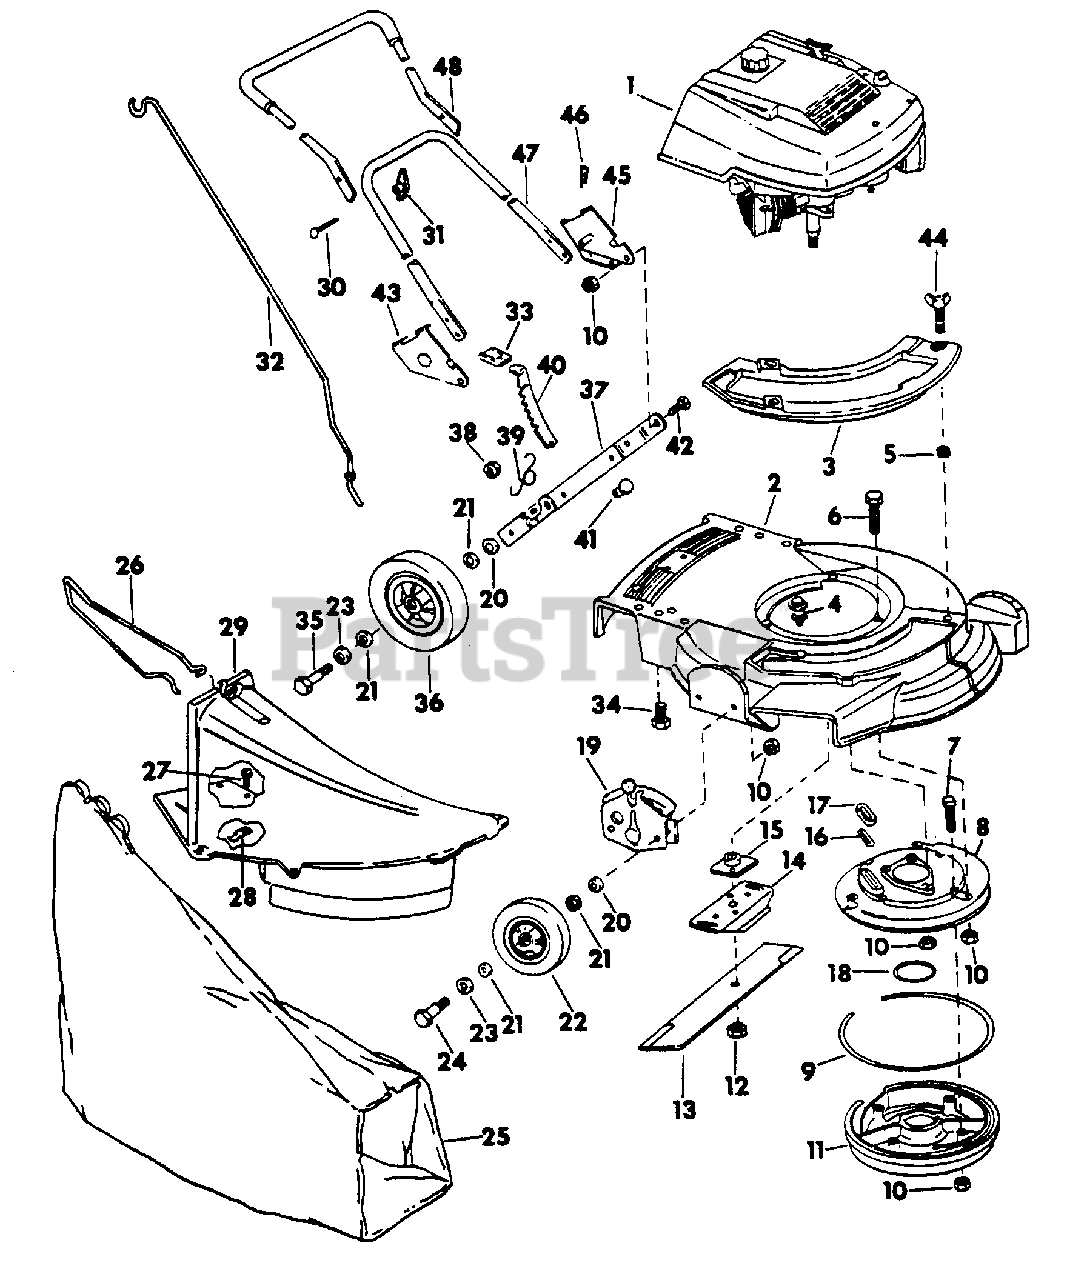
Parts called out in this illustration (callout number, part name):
1	ENGINE, IH
2	HOUSING & GROMMET ASSY. 19 IN.
3	COVER, CHUTE OPENING
4	SCREW, SHOULDER
5	NUT, GROMMET
6	SCREW, MUFFLER PLT TO HSG
7	SCREW, MUFFLER TO PLATE
8	PLATE, MUFFLER
9	GASKET, MUFFLER OUTSIDE
11	COVER, MUFFLER
13	BLADE, 19 IN.
14	STIFFENER, BLADE
15	COLLAR & PLATE
16	GASKET, EXHAUST
17	SLEEVE, EXHAUST GASKET
18	GASKET, MUFFLER INSIDE
19	ADJUSTMENT, HEIGHT
21	WASHER, FELT
22	WHEEL AND TIRE
23	WASHER, WHEEL BOLT HD
24	BOLT, WHEEL FRT SHOULDER
26	GUARD, WHEEL
29	CHUTE ASSY
32	ROD, GRASS BAG
34	SCREW, HANDLE BRACKET
35	BOLT, REAR WHEEL
36	WHEEL & TIRE - 8 IN. REAR
38	NUT, REAR WHEEL BOLT
39	SPRING, HEIGHT ADJ
40	LEVER, REAR HGT ADJ
41	PIN, HEIGHT ADJ LEVER
43	BRACKET & PIN, RH
44	SCREW, WING
45	BRACKET 5 PIN, LH
47	HANDLE, BOTTOM
48	HANDLE & GRIP, TOP
